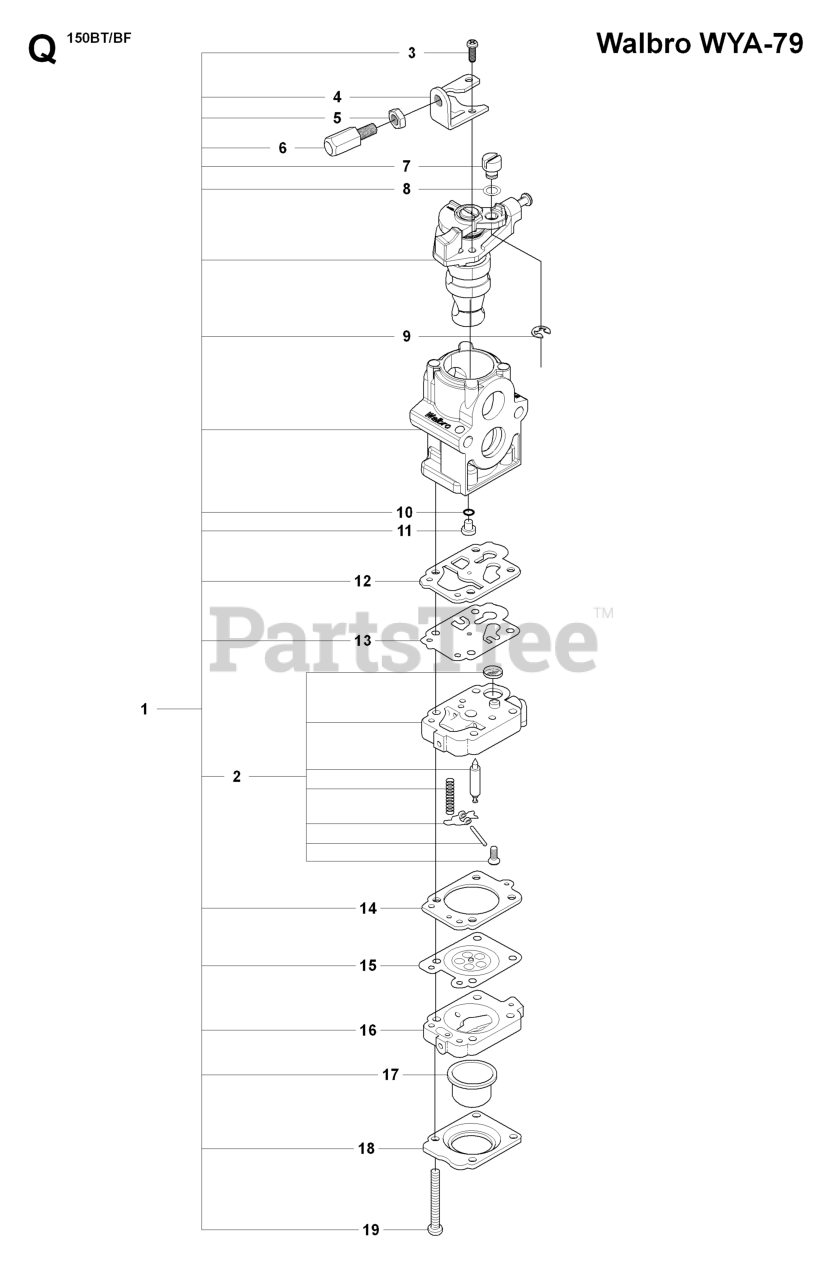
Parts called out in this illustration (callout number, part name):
1	CARBURETOR
2	BODY-A-PUMP
3	SCREW
4	RP_BRACKET
5	NUT
6	SCREW
7	SWIVEL
8	WASHER
10	O-RING
11	JET
12	GASKET
13	DIAPHRAGM
14	GASKET
15	DIAPHRAM
16	BODY
17	PUMP
18	COVER
19	SCREW
